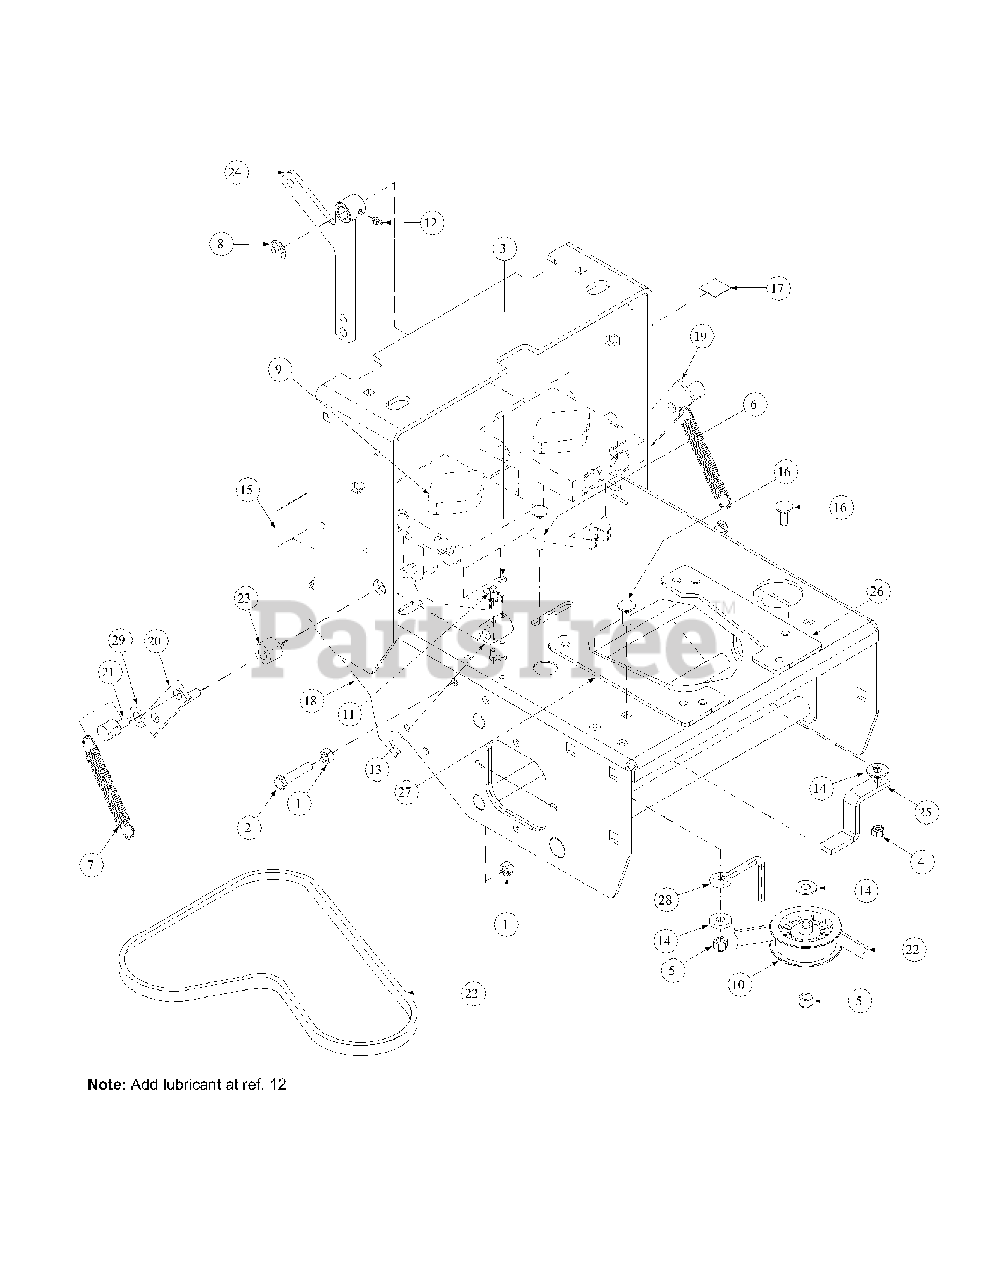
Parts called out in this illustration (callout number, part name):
1	Nut, Hex, 3/8-16 Grade
2	Cap Screw, 3/8-16 x 1-3/4" Grade 5
3	Cap Screw, Square Head Set, 1/4-20
4	Nut, 5/16-18, Nylock
5	Nut, L, Nylon Insert, 3/8-16 Grade A
6	Carriage Bolt, 3/8-16 x 2 Grade 5
7	Spring, Music Wire, LE-093G-9, Plat
8	E-Ring, 5/8" #5113-62
9	Hydro Pump
10	Pulley, Flat Idler W/Adaptor
11	Screw, Cap, Square Head Set, 1/4-20
12	Grease Fitting, 1/4-28 x 3/16 STR
13	Coupling, Trunnion
14	Washer, Idler
15	Decal, "Made In America"
16	Carriage Bolt, 3/8-16 x1.25 Grade 5
17	Label, Mower, Warn, Open Belt Drive
18	Engine Base Assembly, Hydro
19	Hydro Pump Lever Assembly LH
20	Hyrdro Pump Lever Assembly RH
21	Pivot Belt Tightener
23	Bushing, Pump Lever,
24	Bellcrank Clutch
25	Belt Guide, Engine, 36/42/48
26	Spacer, Engine, Right Hand
27	Spacer, Engine, Left Hand
28	Belt Guide, 3.375
29	Flat Washer
